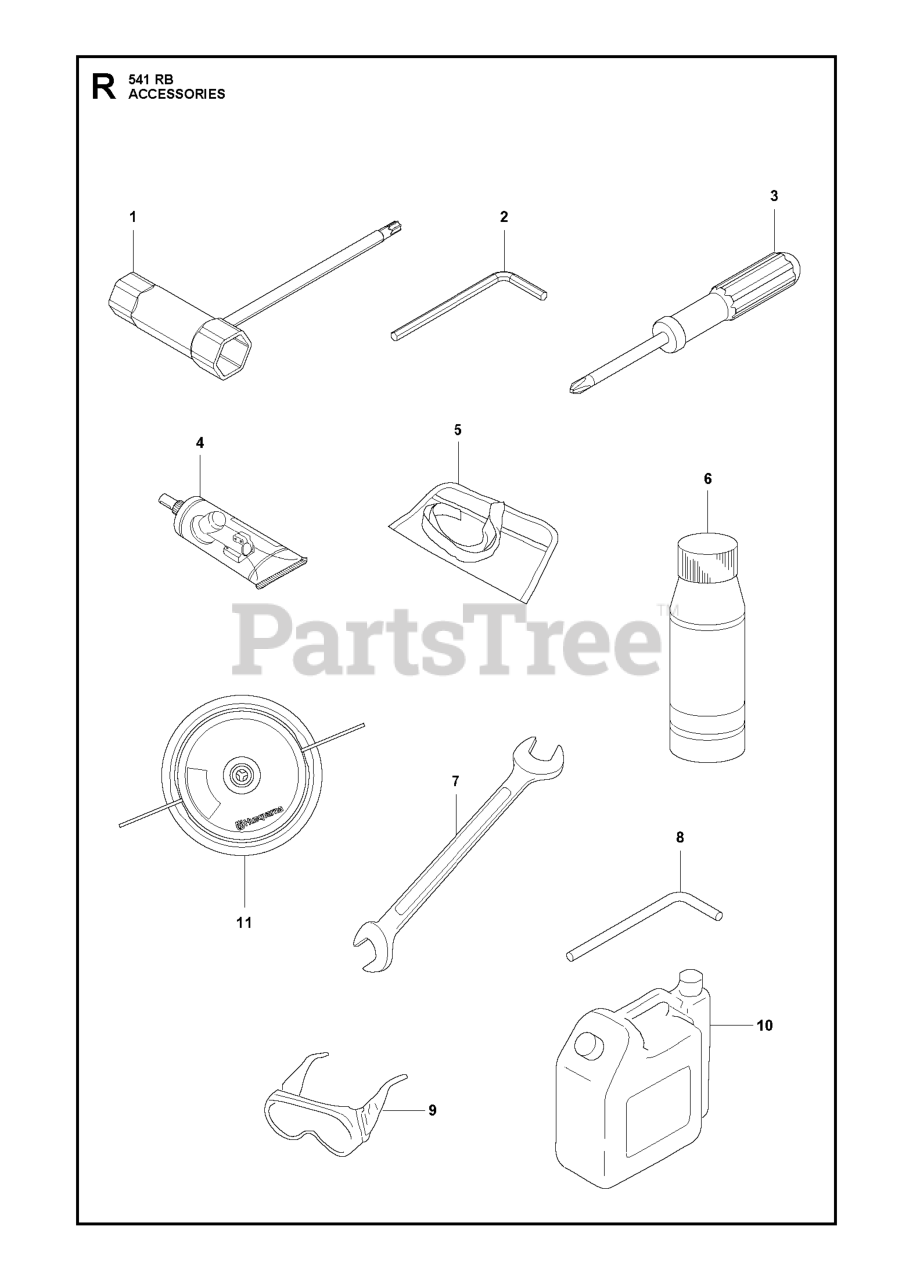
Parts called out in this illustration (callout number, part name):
4	BEVEL GEAR GREASE
6	Air Filter Oil 1l.
7	WRENCH SPANNER
